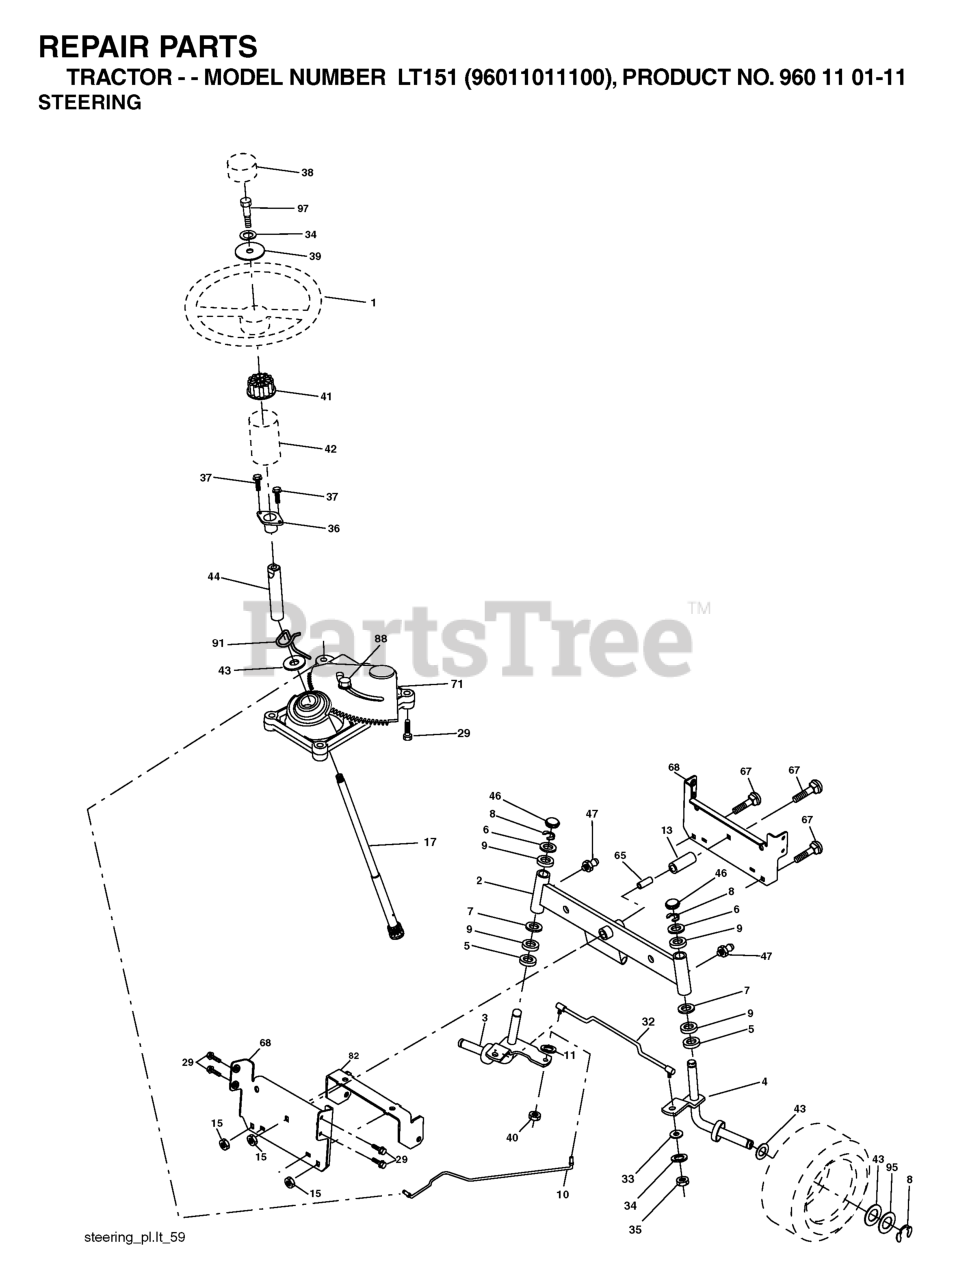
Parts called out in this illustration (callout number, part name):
1	WHEEL.STEERING.LEGEND2.GRY
2	AXLE ASM.
3	SPINDLE.ASM.LH.15"TIRES
4	SPINDLE.ASM.RH.15"TIRES
5	THRUST WASHER
9	BRNG T
10	DRAGLINK.15".TIRES.2001
11	WASHER, LOCK 3/8
13	TUBE, PIVOT AXLE
15	NUT
17	SHAFT STEERING SPLINE
29	SCREW, 3/8-16X3/4
33	WASHER M
34	WASHER.LOCK.HVY.HLCL.SPR.5/16
35	NUT, CROWNLOCK
36	BUSHING, STEERING
37	SCREW.TT.#10-32X.5.3/8.FLANGE
38	INSERT.CAP.STRG.WH.GRAY
39	WASHER.11/32
40	NUT CROWNLOCK 3/8-24
41	ADAPTER, WHEEL STNG..
42	BOOT STEERING
44	SHAFT.EXTEN.STRG.SPLINE
46	CAP.SPINDLE.BLACK
47	FITTING.GREASE.TAPERED
65	SPACER BRACE AXLE
67	BOLT CARRIAGE
68	BRACE.AXLE.15"TIRES
71	STEERING ASM
82	BRACKET.SUSP.CHASSIS.FRONT.15
88	BOLT, SHOULDER 7/16-20
91	CLIP.STEERING
95	WASHER.HARDENED
